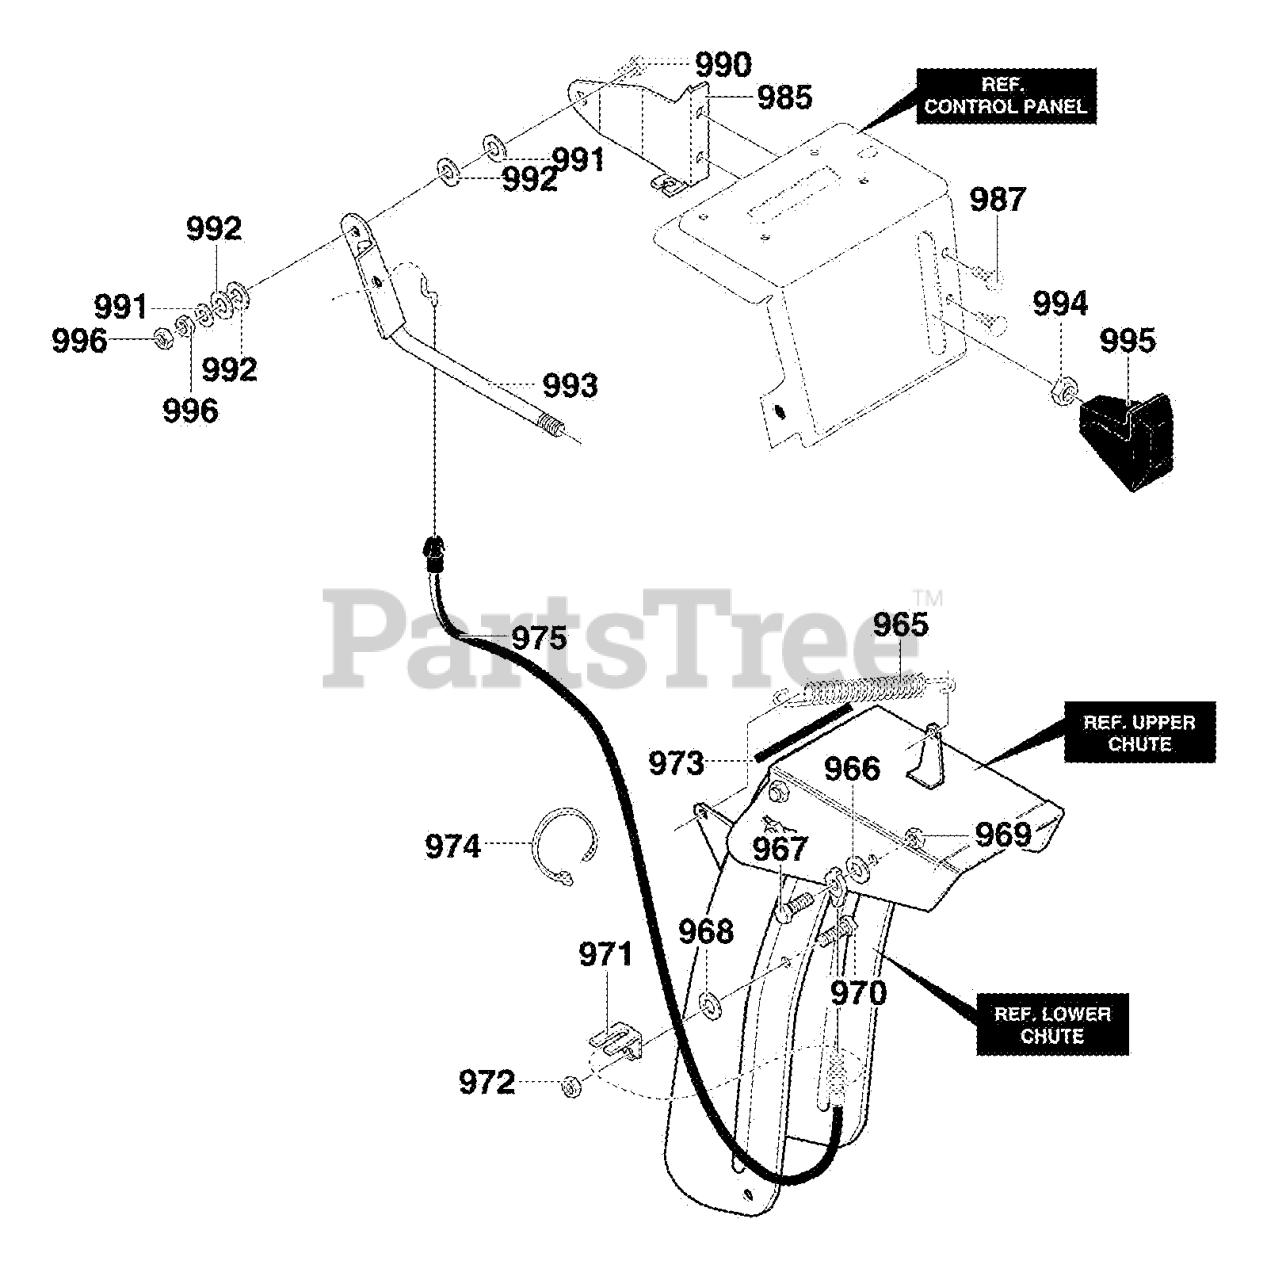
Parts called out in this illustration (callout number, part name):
965	TENSION SPRING
966	FLATWASHER
968	FLATWASHER
971	BRACKET, CABLE CHUTE
973	TRIM STRIP, BLACK
975	CABLE, CHUTE DEFLECTOR
985	BRACKET, SNAP-IN REMOTE
987	SCREW
991	WASHER, FLAT
992	WASHER, SPRING
993	HANDLE, ASSY
995	KNOB, SHIFT
996	NUT
